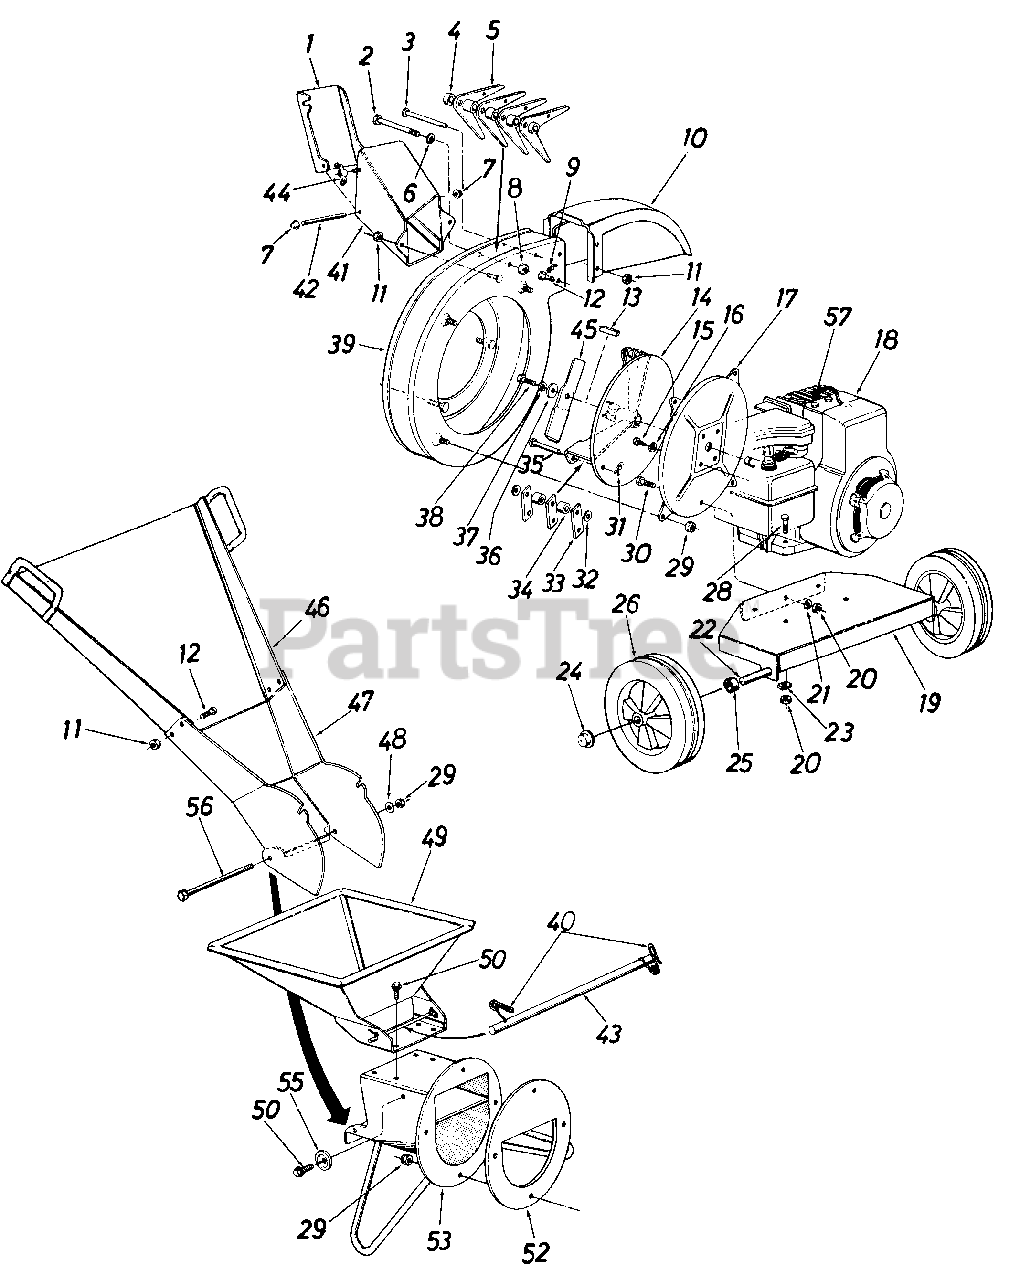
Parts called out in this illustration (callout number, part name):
1	Door Chip It
2	Hex Bolt 1/2-20 x 4.50" Lg.
3	Clevis Pin
4	Flail Spacer 7/32" Lg.
5	Cutting Finger
6	L-Wash. 1/2" I.D.
7	Palnut 3/16" Dia.
8	Hex Jam Nut 1/2-20 Thd.*
9	Cotter Pin 3/32" Dia. x 3/4" Lg.
10	Chute Deflector
11	L-Nut 1/4-20 Thd.
12	Hex Bolt 1/4-20 x .50" Lg.
13	Sq. Key 1/4" x 2.00" Lg.
14	Impeller Assembly
15	Hex Bolt 5/16-24 x 3/4" Lg.
16	L.-Wash. 5/16" I.D.*
17	Hopper to Engine Mtg. Plate
18	Engine
19	Engine Mounting Plate
20	Hex Nut 5/16-24 Thd.
21	L.-Wash. 5/16" I.D.
22	Shaft
23	Special L.-Wash. 5/16" I.D.
24	Push Cap
25	Spacer
26	Wheel Ass'y.-Comp.
28	Hex Bolt 5/16-24 x 1.50" Lg.
29	Elastic Lock Nut 5/16-18 Thd.
30	Hex Bolt 5/16-24 x .62" Lg.*
31	Cotter Pin 1/8" Dia. x 1.00" Lg.*
32	Fl.-Wash. .531" I.D. x 937 O.D. x .09
33	Flail
34	Flail Spacer 23/32" 4.
35	Clevis Pin .50" Dia. x 3.0" Lg.
36	Fl.-Wash. .406" I.D. x 1.25" O.D. Hdn.
37	L.-Wash. 3/8" I.D. H.D.
38	Hex Bolt 3/8-24 x 2.0" Lg. H.T.
41	Chip-It Guide Ass'y.
42	Hinge Pin
43	Release Bar
44	Wing Nut Elastic 1/4-20 Thd.
46	Upper Leaf Ramp Section
47	Lower Leaf Ramp Section
48	Fl.-Wash. 5/16" I.D.
49	Hopper Assembly
50	Hex Wash. Hd. Self-Tap Scr. 5/16-18 x .75" Lg.
52	Back-Up Plate
53	Inlet Guide Assembly
55	Stop Washer
56	Hex Bolt 5/16-18 x 8.38" Lg.
57	Spark Plug Boot
